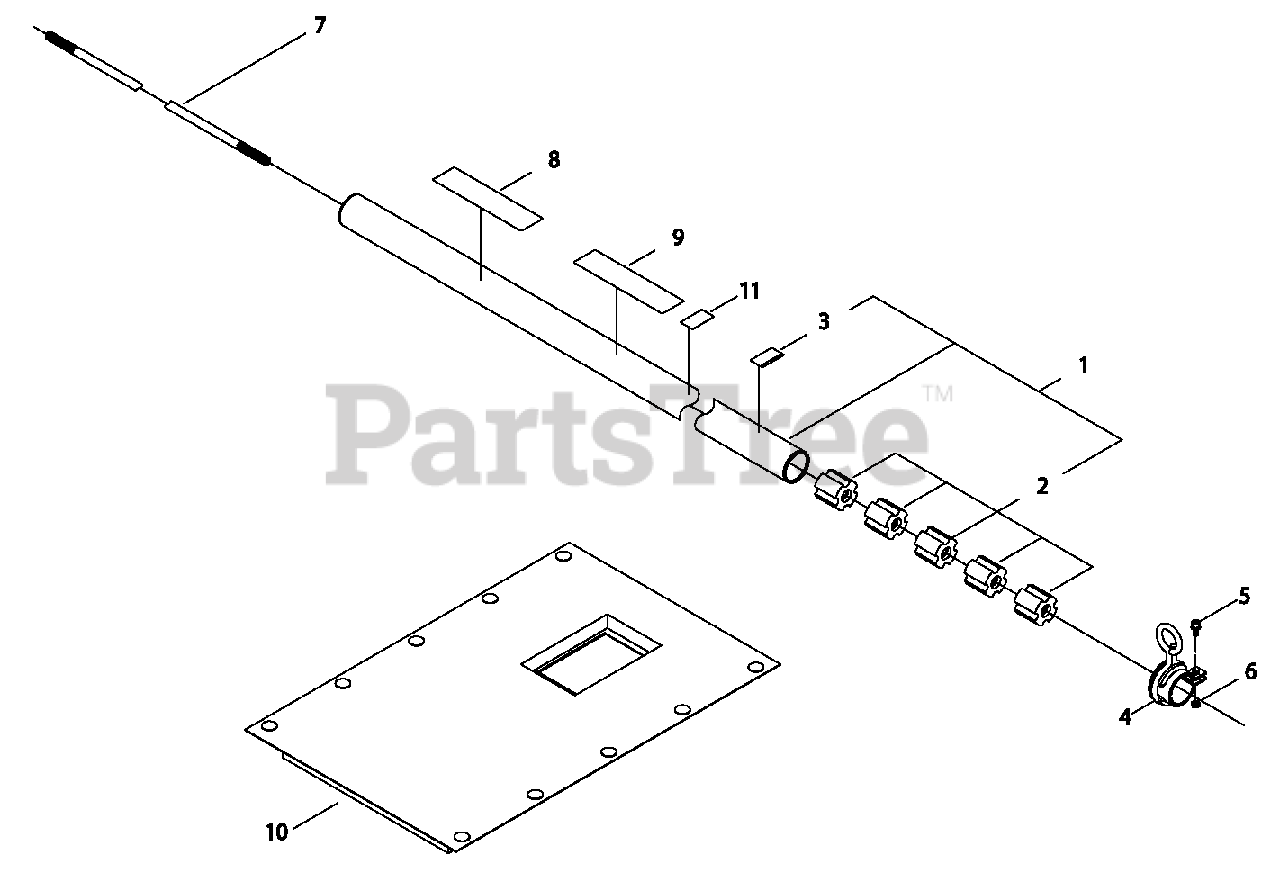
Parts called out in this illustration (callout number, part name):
1	MAIN PIPE ASSY
2	BUSHING
3	LABEL - ALIGNMENT
4	HANGER
5	BOLT M5×12
6	NUT M5
7	DRIVESHAFT
8	LABEL, CAUTION (BLADE CAPABLE)
9	LABEL, SHINDAIWA PROFESSIONAL
10	PROTECTOR
11	LABEL, HANDLE
